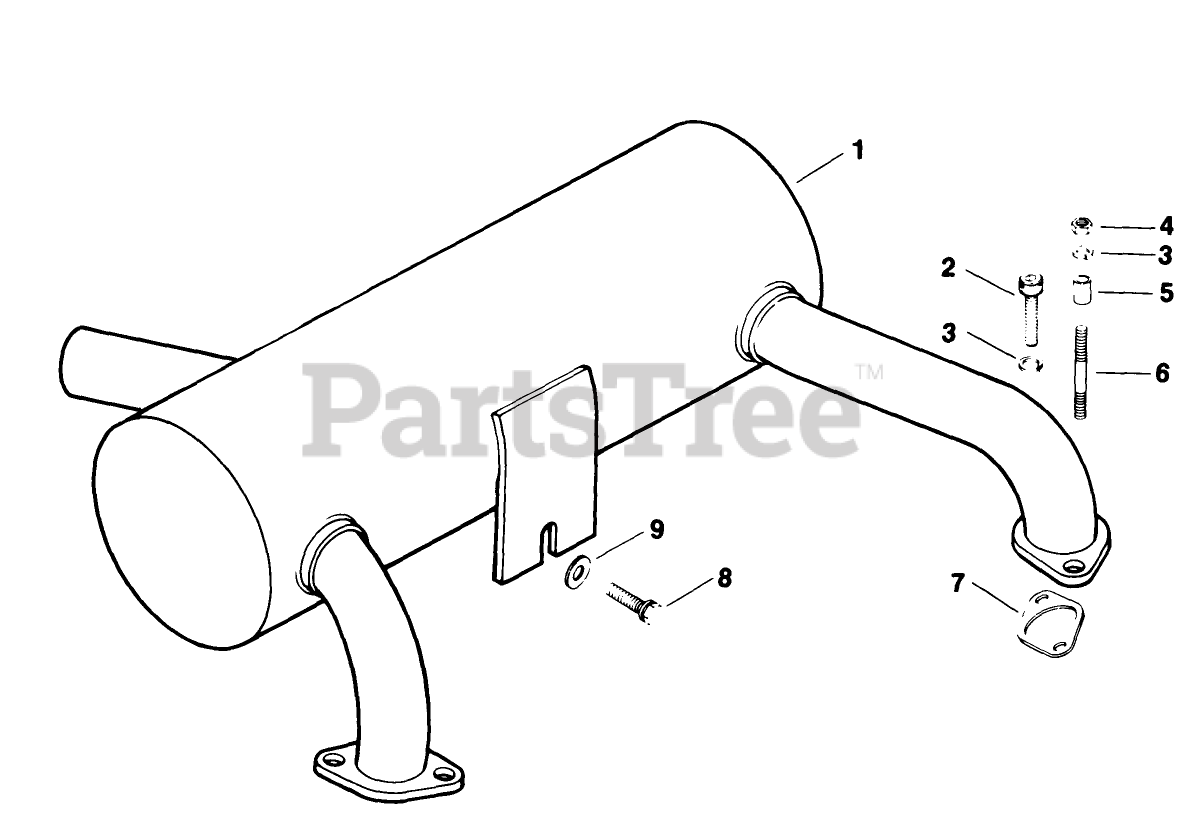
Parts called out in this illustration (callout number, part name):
1	Muffler
2	Screw
3	Washer
4	Nut
7	Gasket Exhaust
8	Screw
9	Washer
